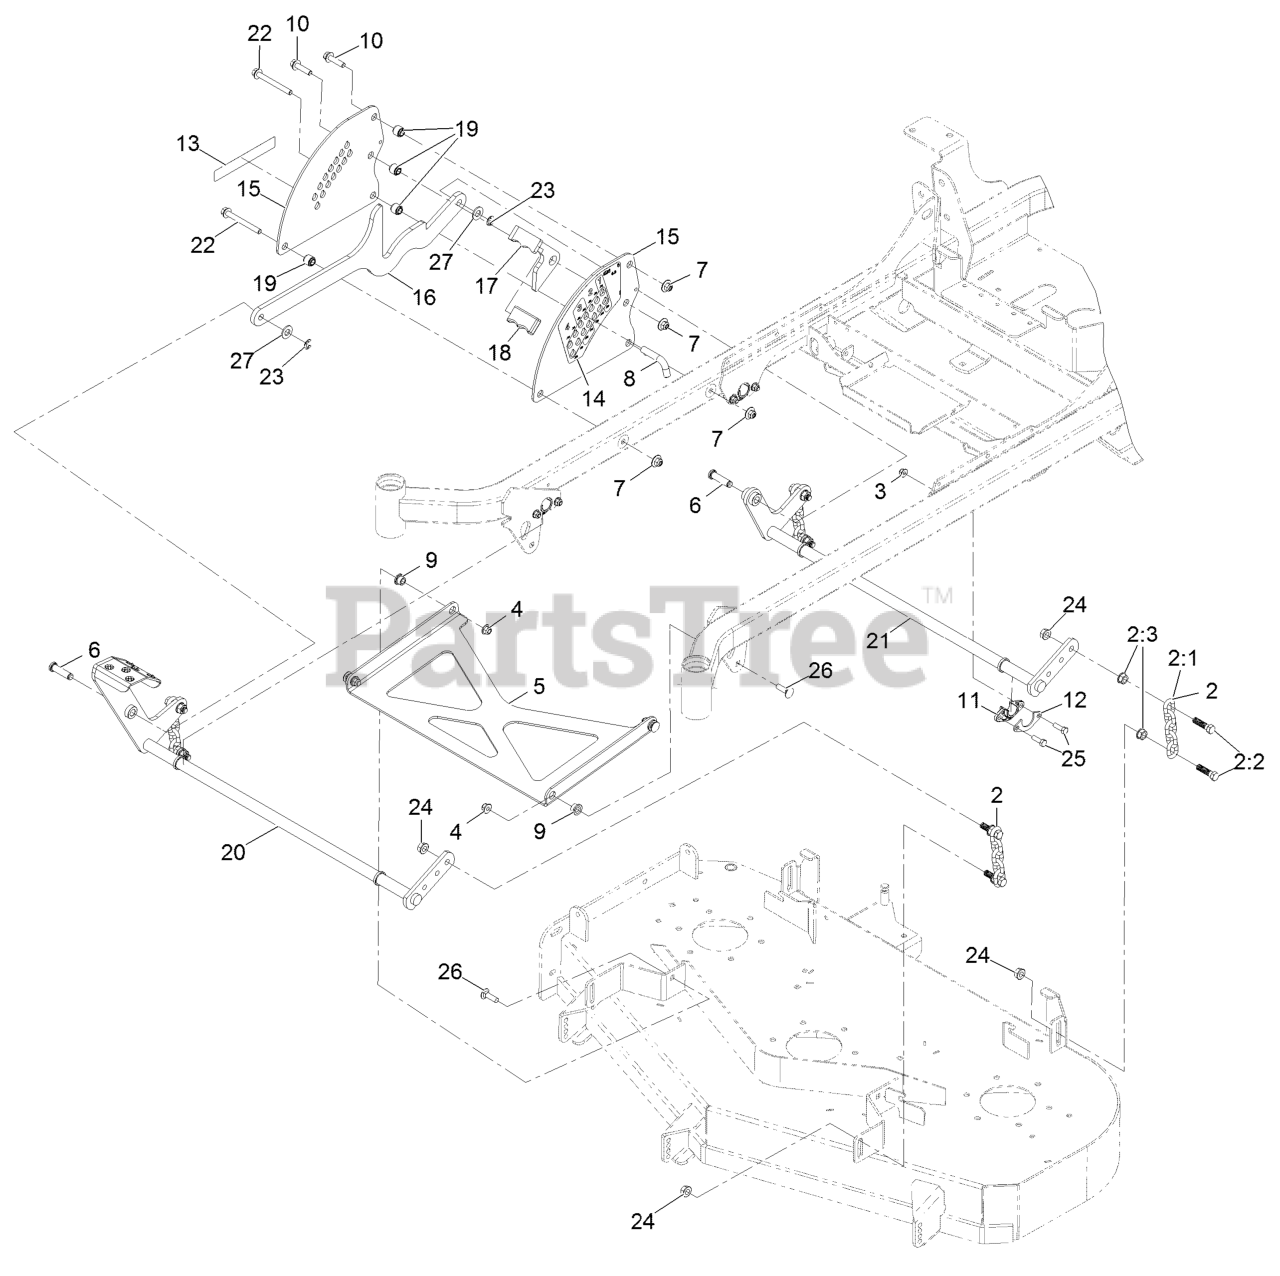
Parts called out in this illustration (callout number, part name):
2	DECK CHAIN ASM
2:1	CHAIN-LIFT, DECK
2:2	SCREW-HH
3	NUT-HF, NI
4	NUT-HF, NI
5	STRUT-DECK
6	PIN-CLEVIS
7	Nut-Nyloc 3/8-16 Flg
8	PIN-HOC
9	BUSHING-FLANGED
10	SCREW-HHF
11	BUSHING-FLANGE
12	GUSSET-LIFT, DECK
13	Decal-S-Series
14	DECAL-HEIGHT OF CUT
15	PLATE,DECK LIFT
17	TRANSPORT LOCK-HOC
18	GRIP-FLAT
19	SPACER-STEP, DOUBLE
20	WLD-DECK LIFT SHAFT FRT
21	WLD-DECK LIFT SHAFT RR
22	SCREW-HHF
23	RING-RETAINING, EXTERNAL
25	SCREW-HH
26	BOLT-CARR
27	WASHER-FLAT
